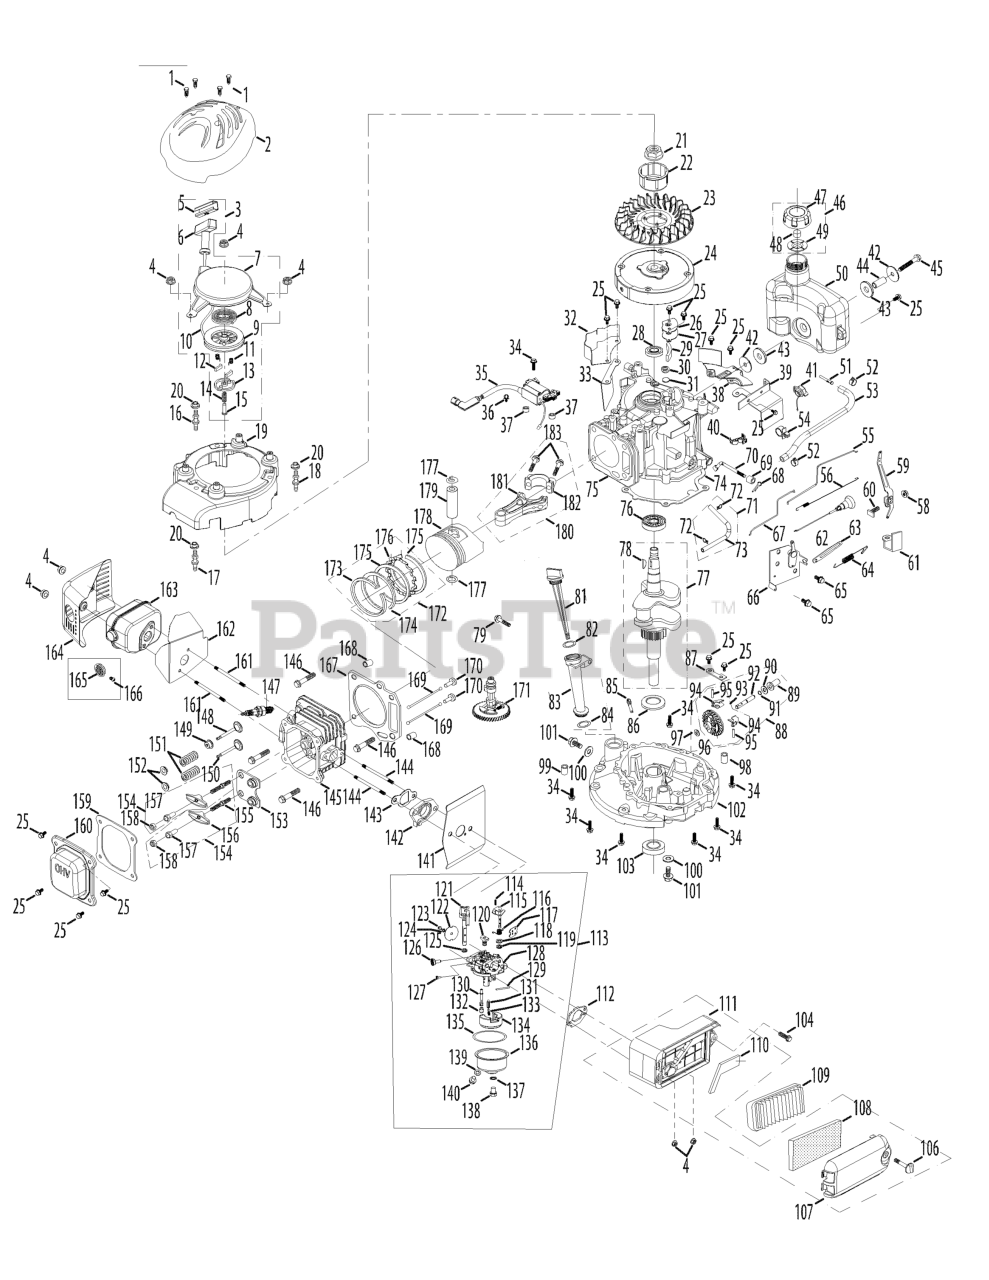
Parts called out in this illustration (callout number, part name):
1	Self-Tapping Bolt,Hilo #12-16 X 1.00"
2	Engine Shroud
3	Recoil Starter Assembly
4	Nut M6 X 10 Mm
5	Starter Handle Insert
6	Starter Handle
7	Starter Housing
8	Recoil & Pulley Assembly
8	Spring
9	Pulley
10	Starter Rope
11	Starter Pawl Return Spring
12	Starter Pawl
13	Pressure Plate
14	Pressure Plate Spring
15	Pressure Plate Bolt
16	Starter/Shroud Stud Black/Ye Zinc
17	Starter/Shroud Stud Front/Ye Zinc
18	Starter/Shroud Stud White/Ye Zinc
19	Inner Shroud
20	Engine Shroud Spacer
21	Flywheel Nut M14
22	Starter Cup
23	Cooling Fan
25	Bolt M6×14
26	Breather Cover Plate
27	Breather Gasket
28	Upper Crankshaft Seal
29	Mesh Screen
30	Breather Spring
31	Breather Valve
32	Engine Brake Cover Plate
33	Label Bracket
34	Bolt M6x 28
35	Ignition Coil Assembly
36	Plastic Clamp 5.8x 9
37	Ignition Coil Spacer
38	Fuel Tank Bottom Bracket
39	Fuel Tank Bracket & On/Off Sw Asm
41	Ignition Switch
42	Fuel Tank Washer
43	Rubber Bushing
44	Fuel Tank Bushing
45	Bolt M8x 50
46	Fuel Cap Assembly
47	Fuel Cap
48	Sponge Insert
49	Vent Gasket
50	Fuel Tank Assembly
51	Fuel Filter
52	Hose Clamp
53	Fuel Hose
54	Plastic Support Clamp
55	Throttle Linkage
56	Throttle Linkage Spring
58	Governor Arm Nut M6
59	Governor Arm
60	Governor Arm Bolt
61	Governor Arm Shield
62	Choke Control
63	Flexible Clamp
64	Governor Spring
65	Bolt M6×12
66	Component Bracket
67	Choke Linkage
68	Governor Cotter Pin
69	Governor Seal
70	Governor Arm Shaft
71	Breather Hose Assembly
72	Breather Hose Clamp
73	Breather Hose
74	Crankcase Cover Gasket
75	Crankcase
76	Main Bearing
77	Crankshaft Assembly
78	Woodruff Key
79	Bolt M6×35
81	Dipstick Assembly
81	Dipstick
82	Dipstick O-Ring
83	Oil Fill Tube Assembly
83	Oil Fill Tube
84	Oil Fill Tube O-Ring
85	Oil Return Tube
86	Crankshaft Thrust Washer
87	Governor Gear Mounting Plate
88	Governor Gear/Shaft Assembly
89	Governor Slide Cap
90	Governor Slide Cap Washer
92	Governor Gear Shaft
93	Governor Gear Assembly
94	Governor Fly Weight
95	Governor Fly Weight Pin
96	Governor Gear
97	Governor Gear Washer
98	Crankcase Cover Dowel 7x14
99	Crankcase Cover Dowel 9x14
100	Oil Drain Plug Washer
100	Drain Plug Washer
101	Oil Drain Plug
101	Drain Plug
102	Crankcase Cover
103	Lower Crankshaft Seal
104	A/F Base Bolt M6×30
106	Air Filter Cover Thumb Screw
107	Air Cleaner Housing Assembly
107	Outer Air Filter Housing
108	Air Cleaner Assembly
108	Pre-Cleaner
109	Air Filter
110	Breather Channel Cover
111	Inner Air Filter Housing
112	Carburetor Gasket Plate
113	Carburetor Assembly
114	Detent Spring
115	Choke Shaft
116	Choke Return Spring
117	Choke Plate
118	Choke Shaft Washer
119	Fiber O-Ring
120	Idle Jet Assembly
121	Throttle Shaft
122	Throttle Plate
123	Throttle Plate Screw
124	Throttle Plate Lock Washer
125	Throttle Shaft Fiber O-Ring
126	Idle Speed Adjusting Screw
127	Idle Mixture Screw
128	Carburetor Body
129	Float Pin
130	(Main Nozzle) Emulsion Tube
131	Needle Valve
132	Main Jet
133	Needle Valve Spring
134	Float
135	Fuel Bowl O-Ring
137	Fuel Bowl Gasket
138	Fuel Bowl Mounting Bolt
139	Fuel Drain Plug Gasket
140	Fuel Drain Plug
141	Carburetor Gasket
142	Carburetor Insulator
143	Carburetor Insulator Gasket
144	Carb Stud M6x92
145	Cylinder Head
146	Head Bolt M8×54
147	Spark Plug
148	Intake Valve
149	Intake Valve Seal
150	Exhaust Valve
151	Valve Spring
152	Valve Spring Retainer
153	Push Rod Guide
154	Rocker Arm Assembly
155	Rocker Arm Stud
156	Rocker Arm
157	Fulcrum Nut
158	Jam Nut
159	Valve Cover Gasket
160	Valve Cover
161	Muffler Stud M6x95
161	Muffler Stud Ass'y
162	Muffler Gasket
163	Muffler Assembly
164	Muffler Shield
165	Spark Arrestor
166	Spark Arrestor Screw
167	Cylinder Head Gasket
168	Cylinder Head Dowel 10x16
169	Push Rod 2 Per
169	Push Rod Kit
170	Tappet
171	Camshaft Assembly
172	Piston Ring Set
173	Upper Piston Compression Ring
174	Lower Piston Compression Ring
175	Piston Oil Ring Segment
176	Piston Oil Ring Expander
177	Piston Pin Snap Ring
178	Piston
179	Piston Pin
180	Connecting Rod Assembly
181	Connecting Rod
182	Connecting Rod Cap
183	Connecting Rod Bolt
